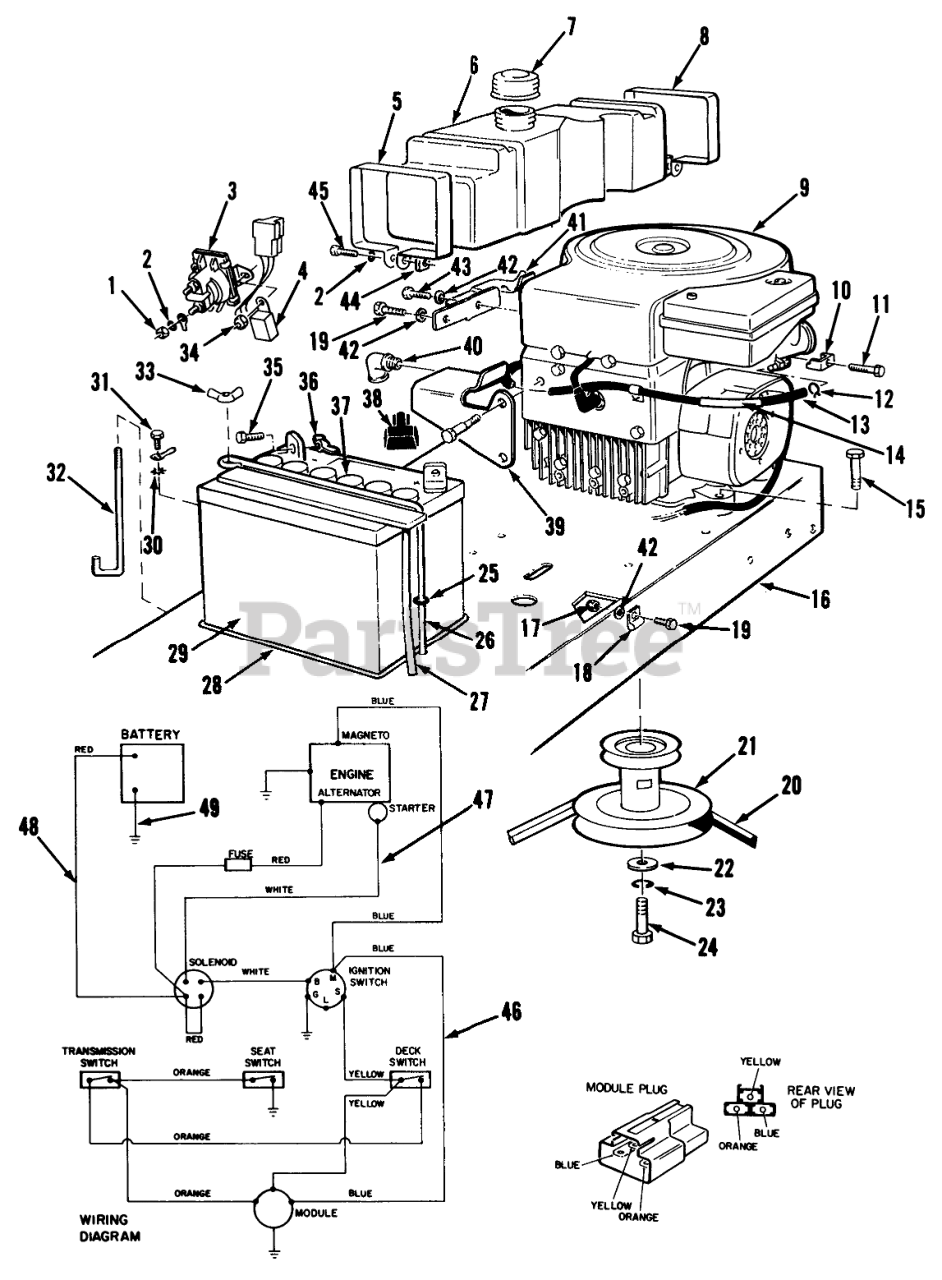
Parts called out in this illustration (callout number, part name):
1	NUT-JAM
2	WASHER-LOCK
3	SOLENOID
4	Module Interlock
5	Retainer-Front
6	TANK-5 QT GAS
7	GAS CAP ASM
8	Retainer-Rear
10	CLAMP-CASING
11	SCREW W ENGINE
12	CLAMP-HOSE
13	HOSE-FUEL
14	SUPPORT-FUEL LINE
15	SCREW-HH
16	HEAT SHRINK TUBING
17	NUT-LOCK, NI
18	CLAMP
19	SCREW-HH
20	V-BELT, TRACTION
21	PULLEY
22	WASHER-FLAT
23	WASHER-LOCK
24	SCREW-HH
25	O-RING
26	HOLDDOWN-BATTERY
27	TUBE-BATT DRAIN/80-2600
28	PAD-SKID, ANTI
29	Battery 5/16
30	WASHER-LOCK, INTERNAL
31	SCREW-HHF
32	POST-BATTERY
33	NUT-WING
34	NUT-LOCK, CONE
35	SCREW-HH
36	NUT-WING
37	CAP-BATTERY
38	BOOT-TERMINAL
39	FRT TANK MTG BRKT B
40	ELBOW-STREET, 90 DEG
41	Retainer-Front
42	WASHER-PLAIN
43	SCREW-HH
44	NUT-SQUARE
45	SCREW-HSH
46	WIRING HARNESS
47	STARTER WIRE HARNESS
48	WIRE ASM
49	WIRE ASM(BATT/GRD.
